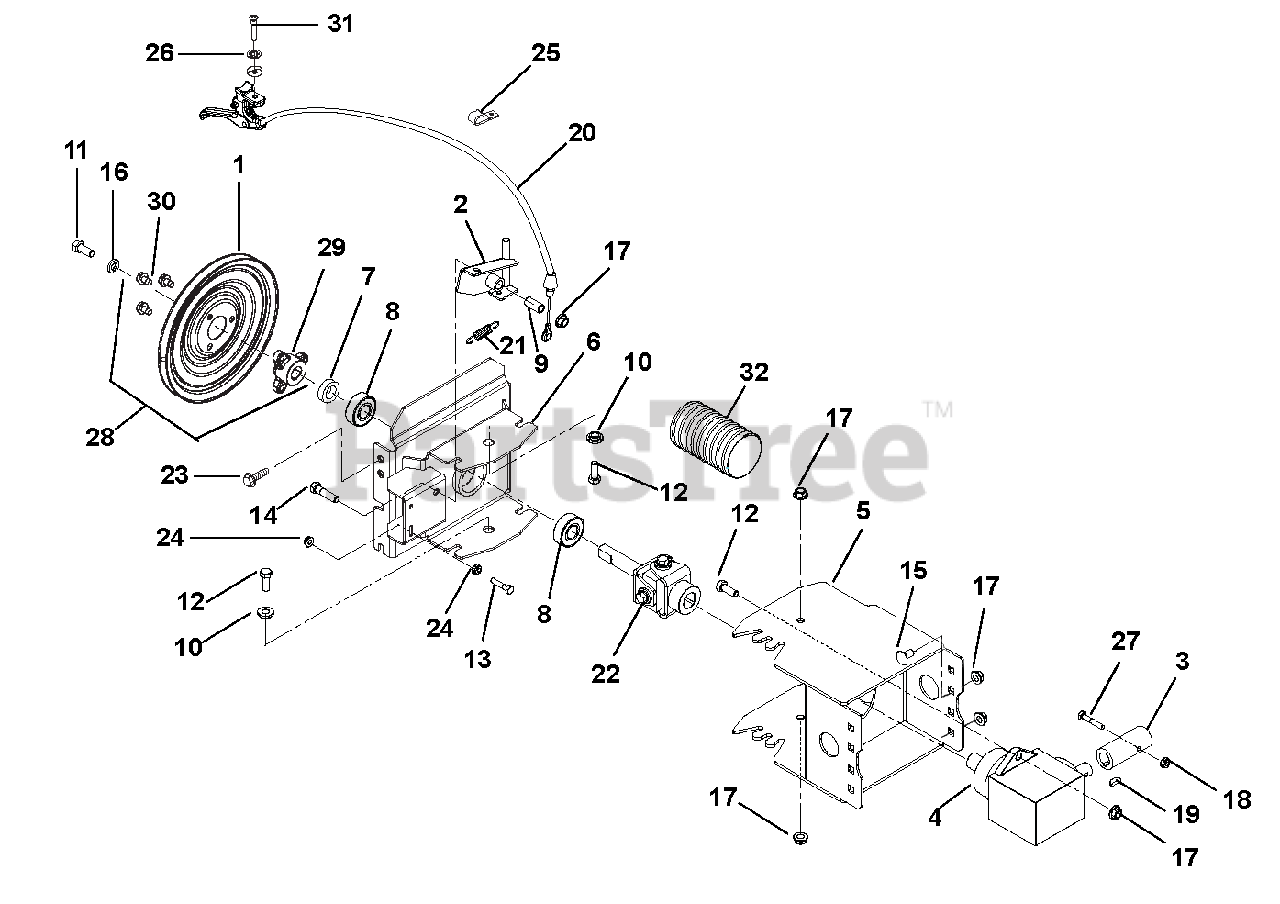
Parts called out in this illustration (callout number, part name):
1	PULLEY,SPIN FORM SINGLE GROOVE
2	ARM, PIVOT LOCK
3	HUB, COUPLING
4	GEAR BOX ASSEMBLY
5	ADAPTER WITH DECAL,BRUSH FRAME
6	ADAPTER, FRAME-20000 SERIES
7	SPACER .755X1.250X.370
8	BRG-BALL .750X1.781X.61
9	BSHG-SLV .385X.500X1.045
10	BSHG-FLG .406X.88X.270X.140
11	BLT-HEX .31-24X.75 YWZC GR5
12	@BLT-HEX .38-16X1.00 GR5 YWZC
13	@BLT-HEX .25-20X1.50 GR5 YWZC
14	@BLT-HEX .38-16X1.75 GR5 YWZC
15	@BLT-RDHDSQNK .38-16X.75 G5YZ
16	WSHR-LK .312X.097 HVY YWZC
17	@NUT-LK-TOP-FLG .38-16 YWZC
18	@NUT-LK-TOP-FLG .25-20 YWZC
19	KEY-WDRF .188X.75X.313 SAE 9
20	CABLE, REMOTE BRUSH LOCK
21	SG-TENS .06X.46X2.00
22	U-JOINT ASSY
23	@SCR-TAP .31-18X.75 HWH TR YWZ
24	@NUT-SPNLK-FLG .25-20 YWZC
25	J-CLAMP
26	WSHR-LK-INT .250 TH TYA
27	@BLT-HEX .25-20X1.75 GR5 YWZC
28	PULLEY WITH HUB
29	PULLEY HUB, BOLT-ON D-BORE .75
30	@SCR-TAP .31-18X.50 HWH TR YWZ
31	SCR-MCH .25-20X1.50 OVAL HD
32	HOSE 4" X 7" FLEX TUBE PV
